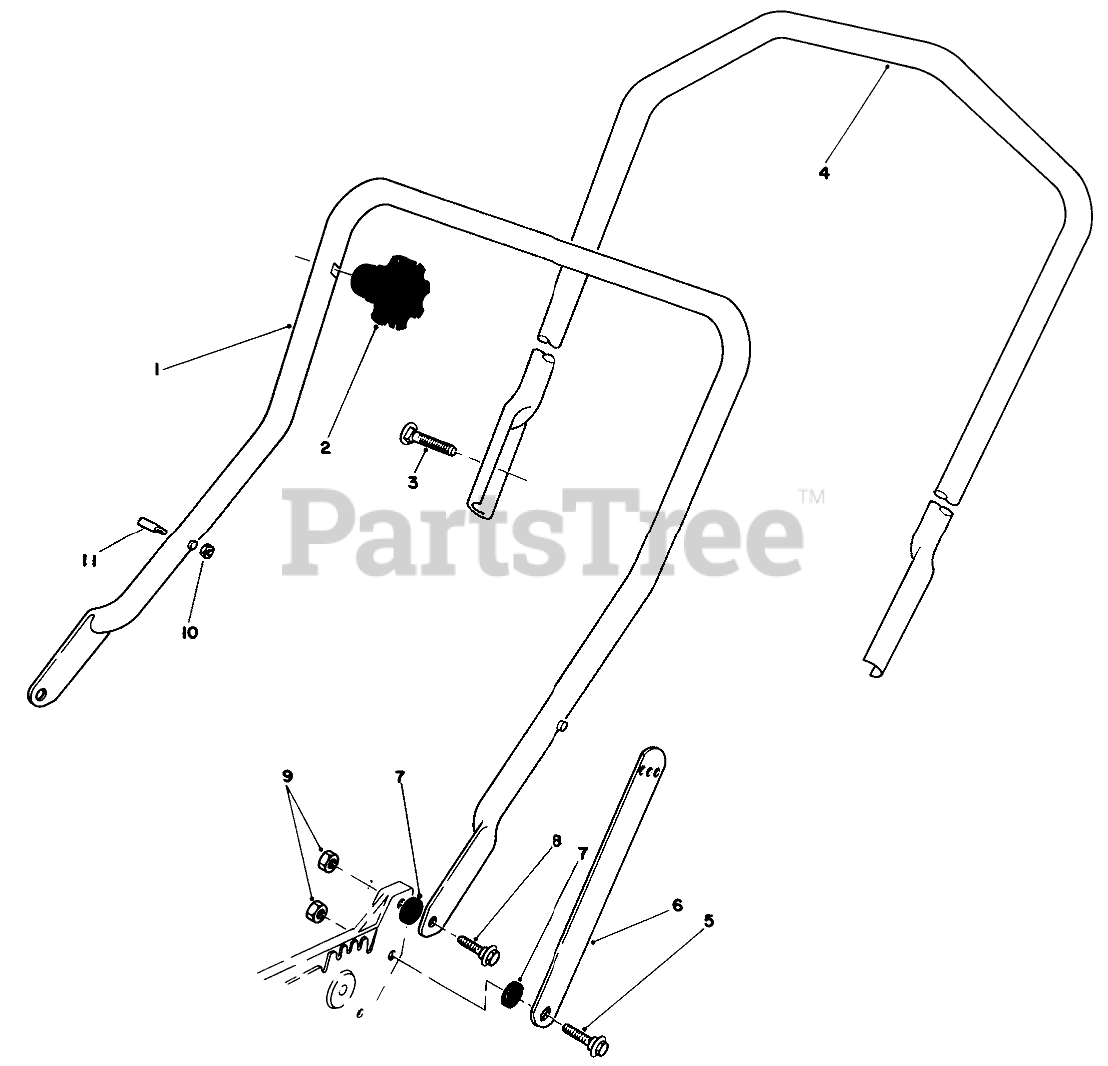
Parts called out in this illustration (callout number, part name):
1	LOWER HANDLE ASM
3	5/16-18 X 2 HNDLE SCREW
4	Handle-Upper
5	SCREW-SHOULDER
6	Handle Latch
7	SPACER
8	SCREW-SHOULDER
9	NUT-LOCK, NI
10	NUT-LOCK, NI
11	HANDLE PIN
